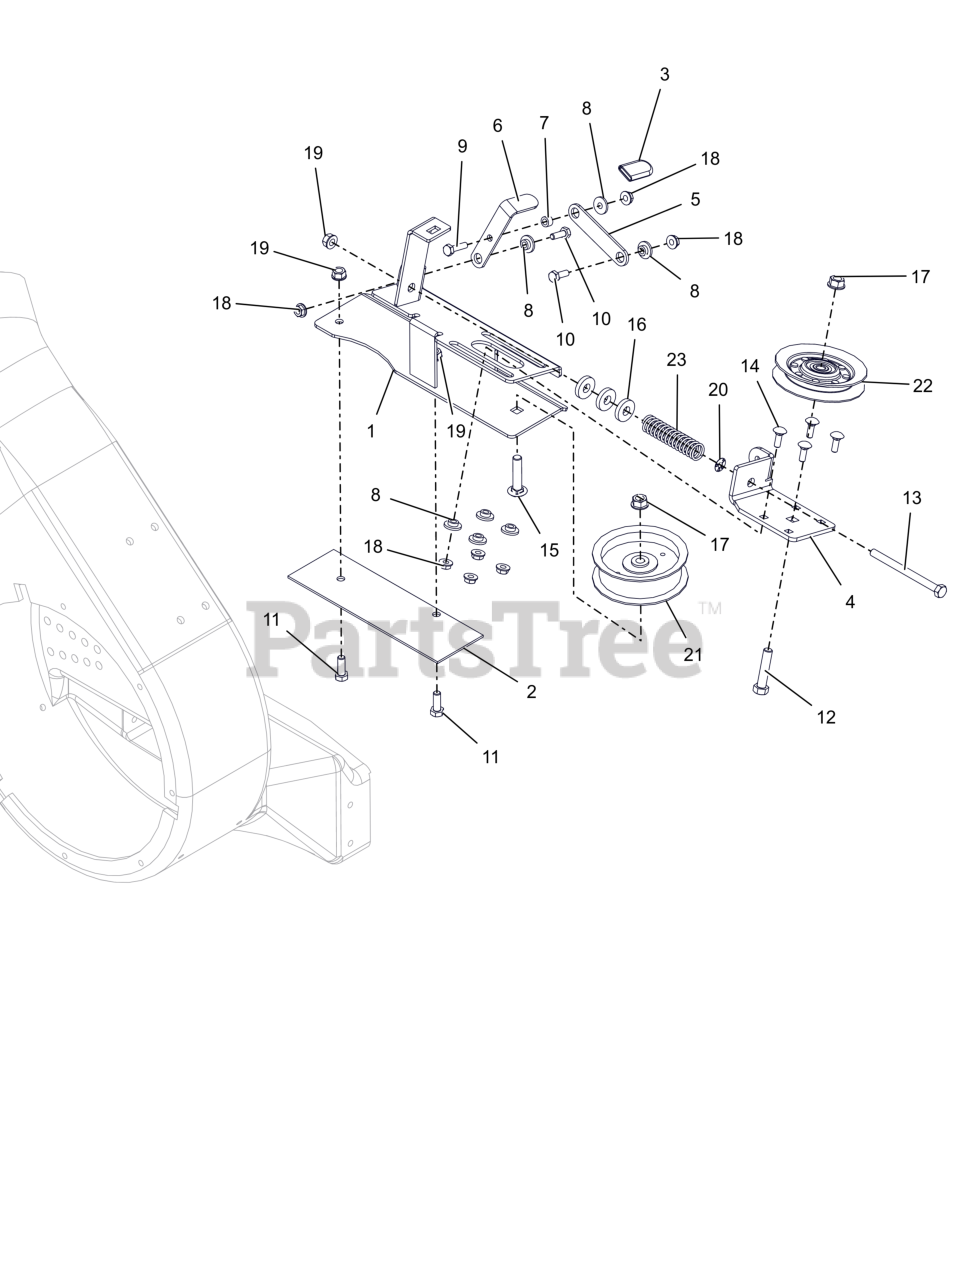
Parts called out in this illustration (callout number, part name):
1	WELDMENT, IDLER MOUNT -2015
2	PLATE,BACK
3	GRIP, SEAT LEVER, GREY
4	BRACKET, ADJ. PULLEY IDLER
5	LINK, TENSIONER
6	HANDLE, TENSIONER
7	BUSHING, .26 ID X .44 OD X .26
8	BSHG-FLG .265X.437X.250X.750
9	BLT,HEX .25-20X1.00 G5 ZCC
10	BLT, HEX .25-20X.75 G5 ZCC
11	BLT, HEX .31-18X.875 G5 ZCC
12	BLT, HEX .38-16X1.75 G5 ZCC
13	BLT, HEX .31-18X4.00 G5 ZCC
14	BLT, RHSN .25-20X.750 G5 ZCC
15	BLT, RHSSN .38-16X1.75 G5 ZCC
16	WSHR, FLT .406X1.00X.188 ZCC
17	NUT-LK-TOP-FLG .38-16 ZC120
18	NUT-LK-TOP-FLG .250-20 GF ZCC
19	NUT-LK-TOP-FLG .312-18 GF ZCC
20	NUT-PUSH .312
21	IDLER, FLG .38ID X 3.50
22	V-IDLER, 4.00X.38
23	SG-COMP .092X.77X3.13 WLD 36
